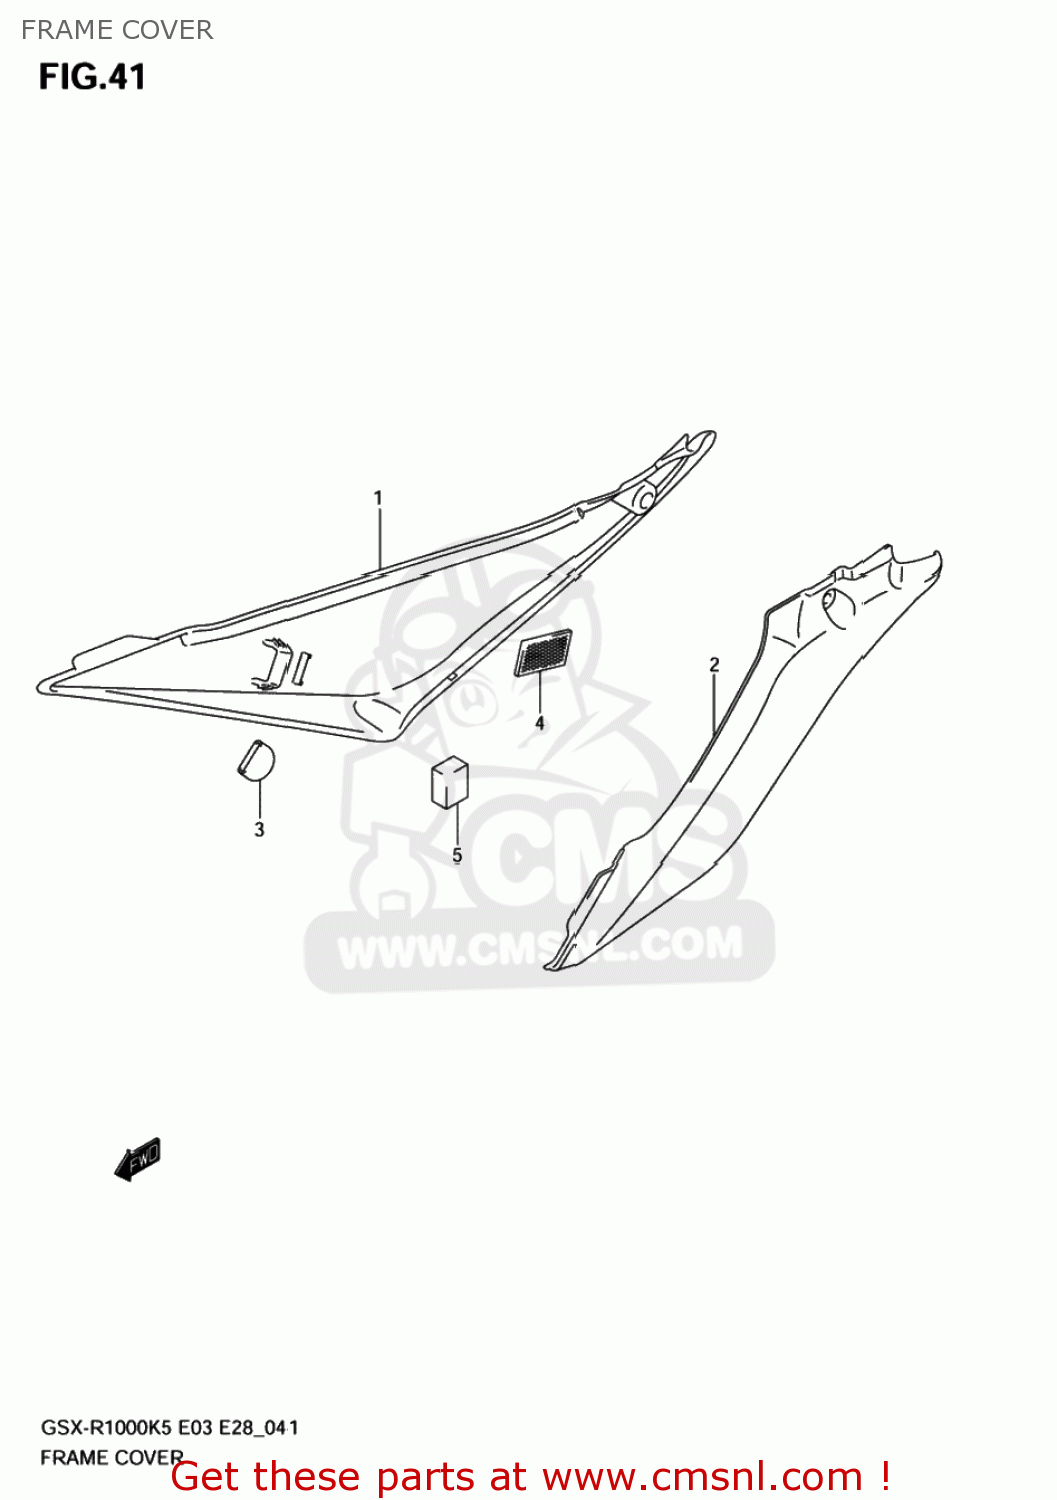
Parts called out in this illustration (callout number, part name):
1	COVER,FRAME,R(BLACK)
2	COVER,FRAME,L(BLACK)
3	CUSHION,FUEL TANK SIDE
4	FASTENER
5	CUSHION
